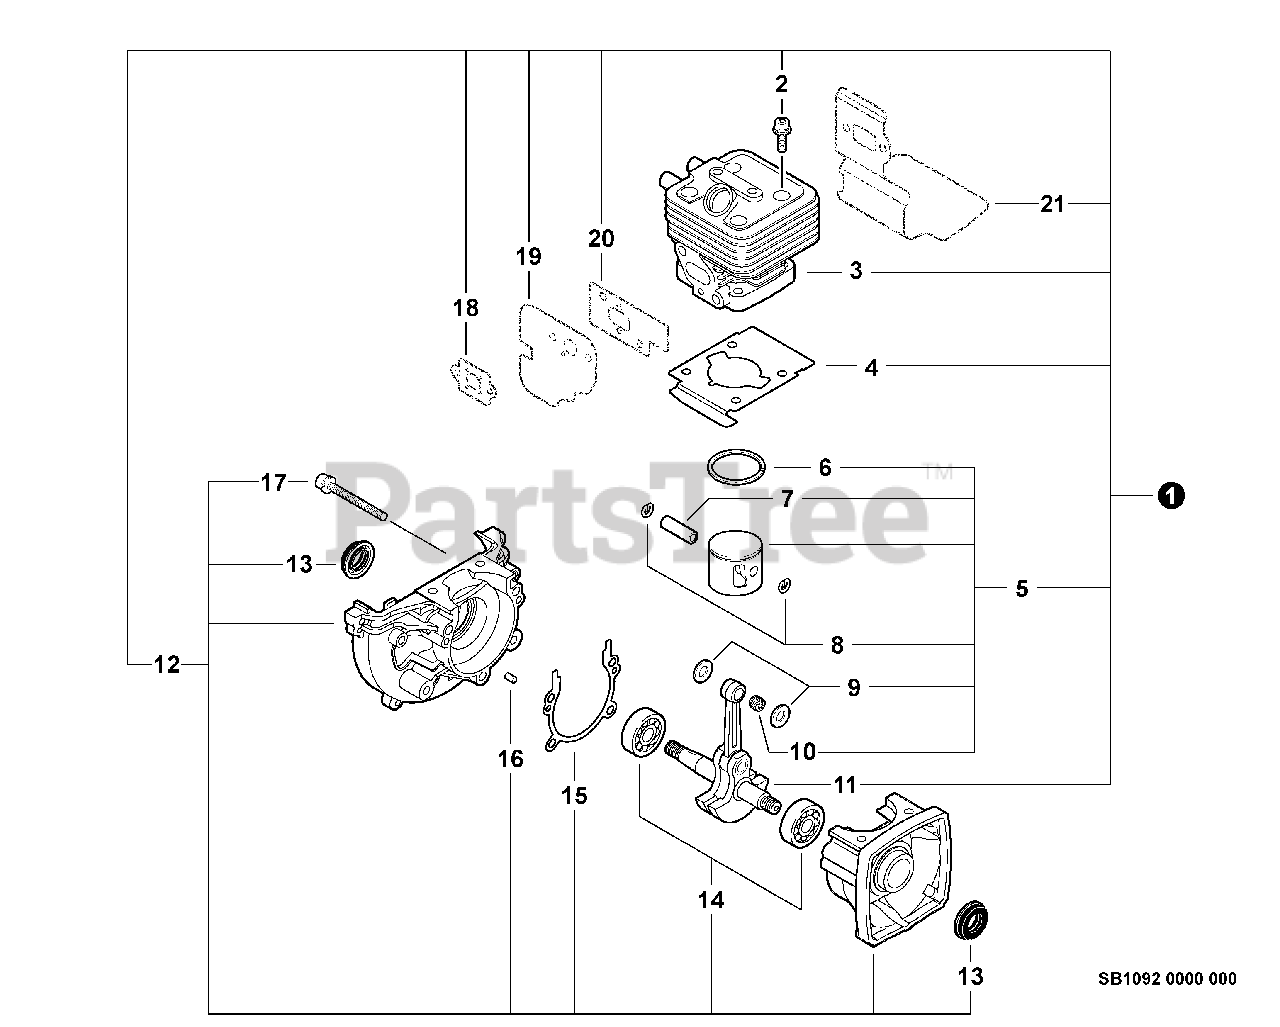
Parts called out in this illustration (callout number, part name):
1	SHORT BLOCK
2	BOLT 5×25
3	CYLINDER
4	GASKET, CYLINDER
5	PISTON KIT
6	RING, PISTON
7	PIN, PISTON
8	RING, SNAP
9	WASHER, THRUST
10	BEARING, NEEDLE 8
11	CRANKSHAFT ASSY
12	CRANKCASE KIT
13	SEAL, OIL 12
14	BEARING, BALL - 6201 C3
15	GASKET, CRANKCASE
16	PIN, LOCATING 4×8
17	BOLT 5×28
18	GASKET, INTAKE
19	GASKET, INTAKE
20	GASKET, INTAKE
21	SHIELD, EXHAUST
